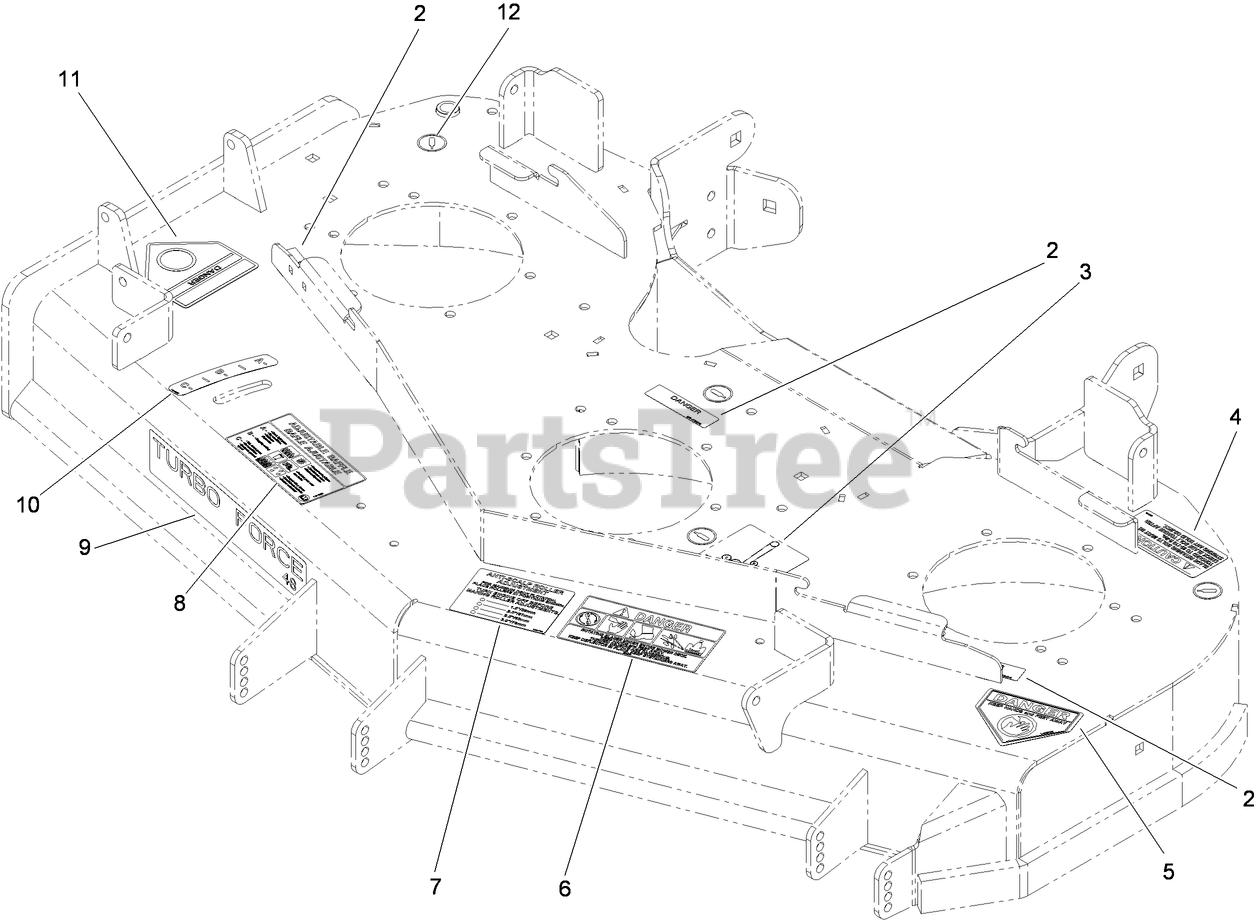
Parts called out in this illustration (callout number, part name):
2	DECAL-COVER, MISSING
3	DECAL-ROUTING, DECK BELT
4	DECAL-TORQUE
5	DECAL-DANGER
6	DECAL-DANGER, THROWN OBJECT
7	DECAL-SCALP, ANTI
8	DECAL-ADJUSTMENT, BAFFLE
10	DECAL-SETTING, BAFFLE
11	DECAL-DANGER
12	DECAL-GREASE
